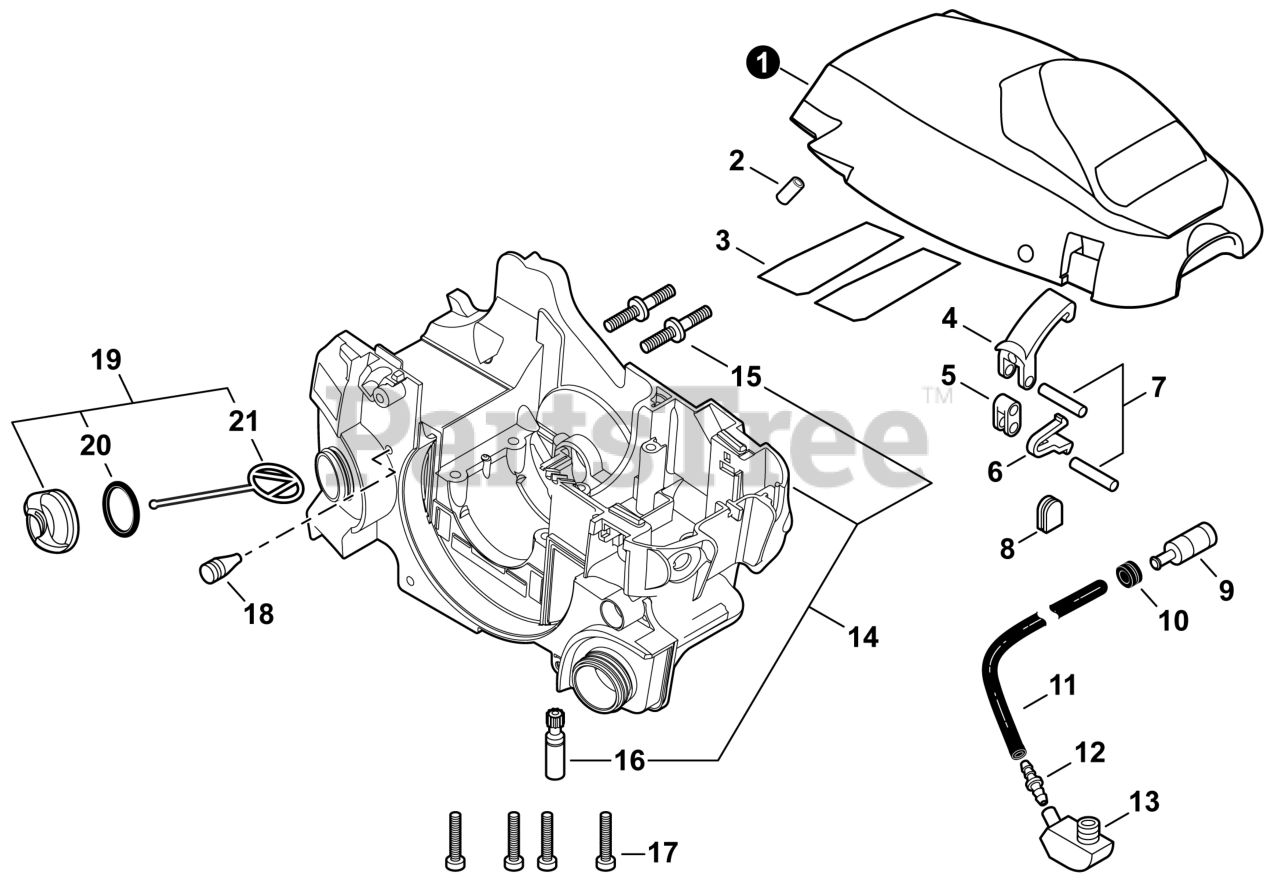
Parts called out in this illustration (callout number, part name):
1	COVER, ENGINE
2	BUSHING 3x7x10
3	SHIELD, HEAT
4	LATCH, ENGINE COVER
7	PIN 4x17.8
9	FILTER, OIL
11	PIPE 3x6x185 MM BLACK
12	CONNECTOR, PIPE
13	GROMMET, OIL
14	HOUSING ASSY, ENGINE
15	BOLT, STUD 8
16	AUTO-OILER ASSY
17	BOLT, TORX 5x30
18	VENT ASSY
19	CAP ASSY - BLACK
20	O-RING 18
21	CONNECTOR, CAP L= 60 MM
